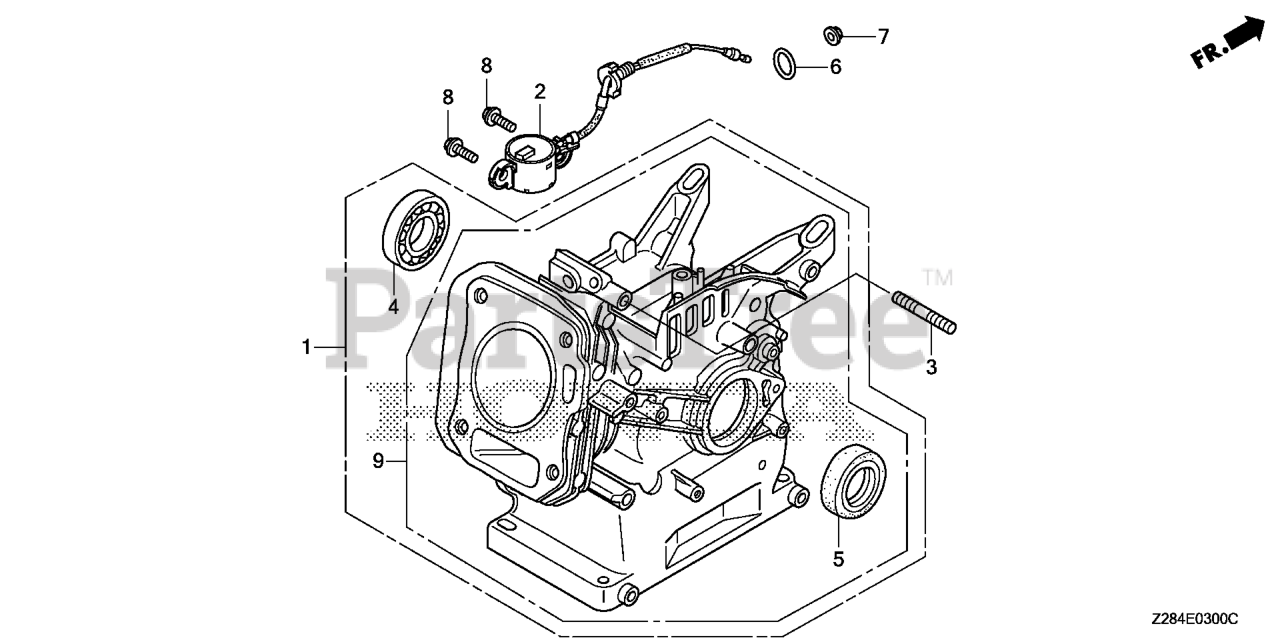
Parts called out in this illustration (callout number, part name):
1	CYLINDER ASSY.
2	SWITCH ASSY., OIL LEVEL
3	BOLT, STUD (6X25)
4	BEARING, RADIAL BALL (6205)
5	OIL SEAL (25X41X6)
6	O-RING (14MM) (ARAI) Use up to Engine SN 2949254.
6	O-RING (14MM) (NOK)
7	NUT, FLANGE (10MM)
8	BOLT, FLANGE (6X12) Use up to Engine SN 1543277.
